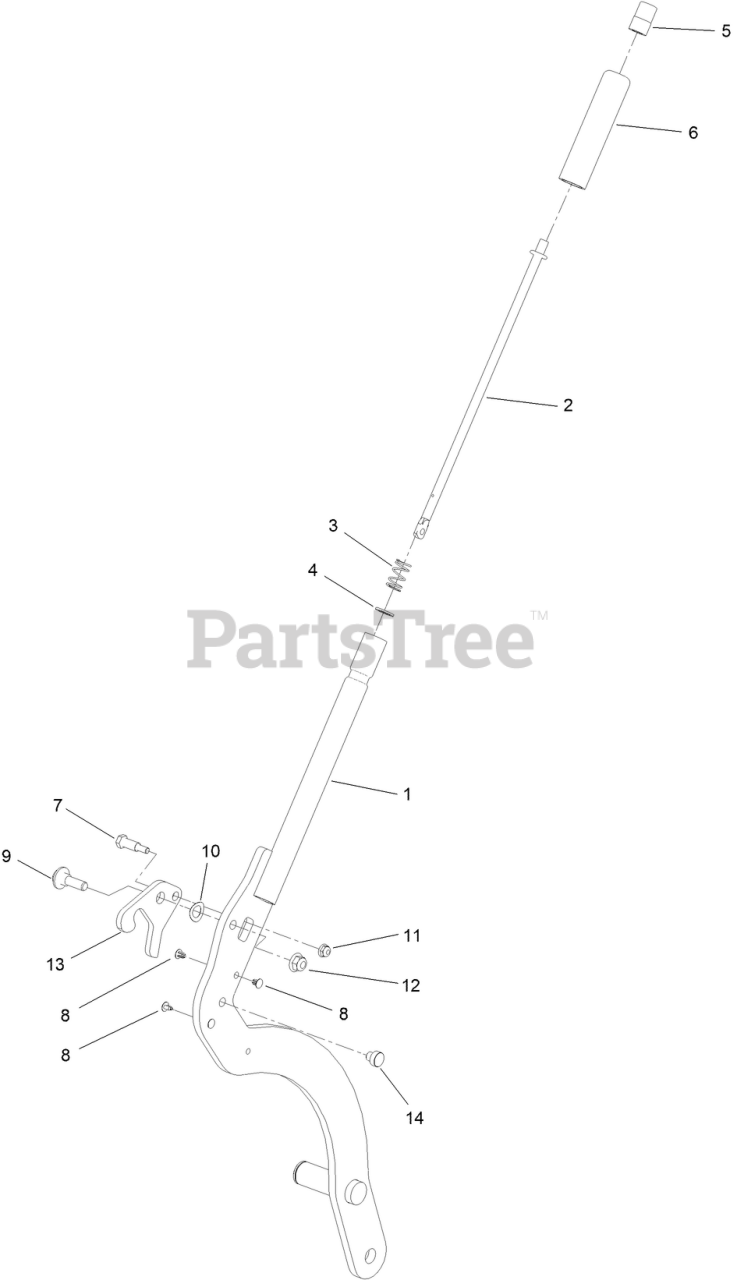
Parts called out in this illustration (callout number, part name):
1	LIFT LEVER ASM [RED]
2	ROD-LATCH, RELEASE
3	SPRING-COMPRESSION
4	WASHER-SPECIAL
7	BOLT-SHOULDER
9	SCREW-SHOULDER, HWH
10	WASHER-SPRING
11	NUT-HF
12	NUT-HF, NI
13	LATCH-HOC
14	PLUG-WEAR
